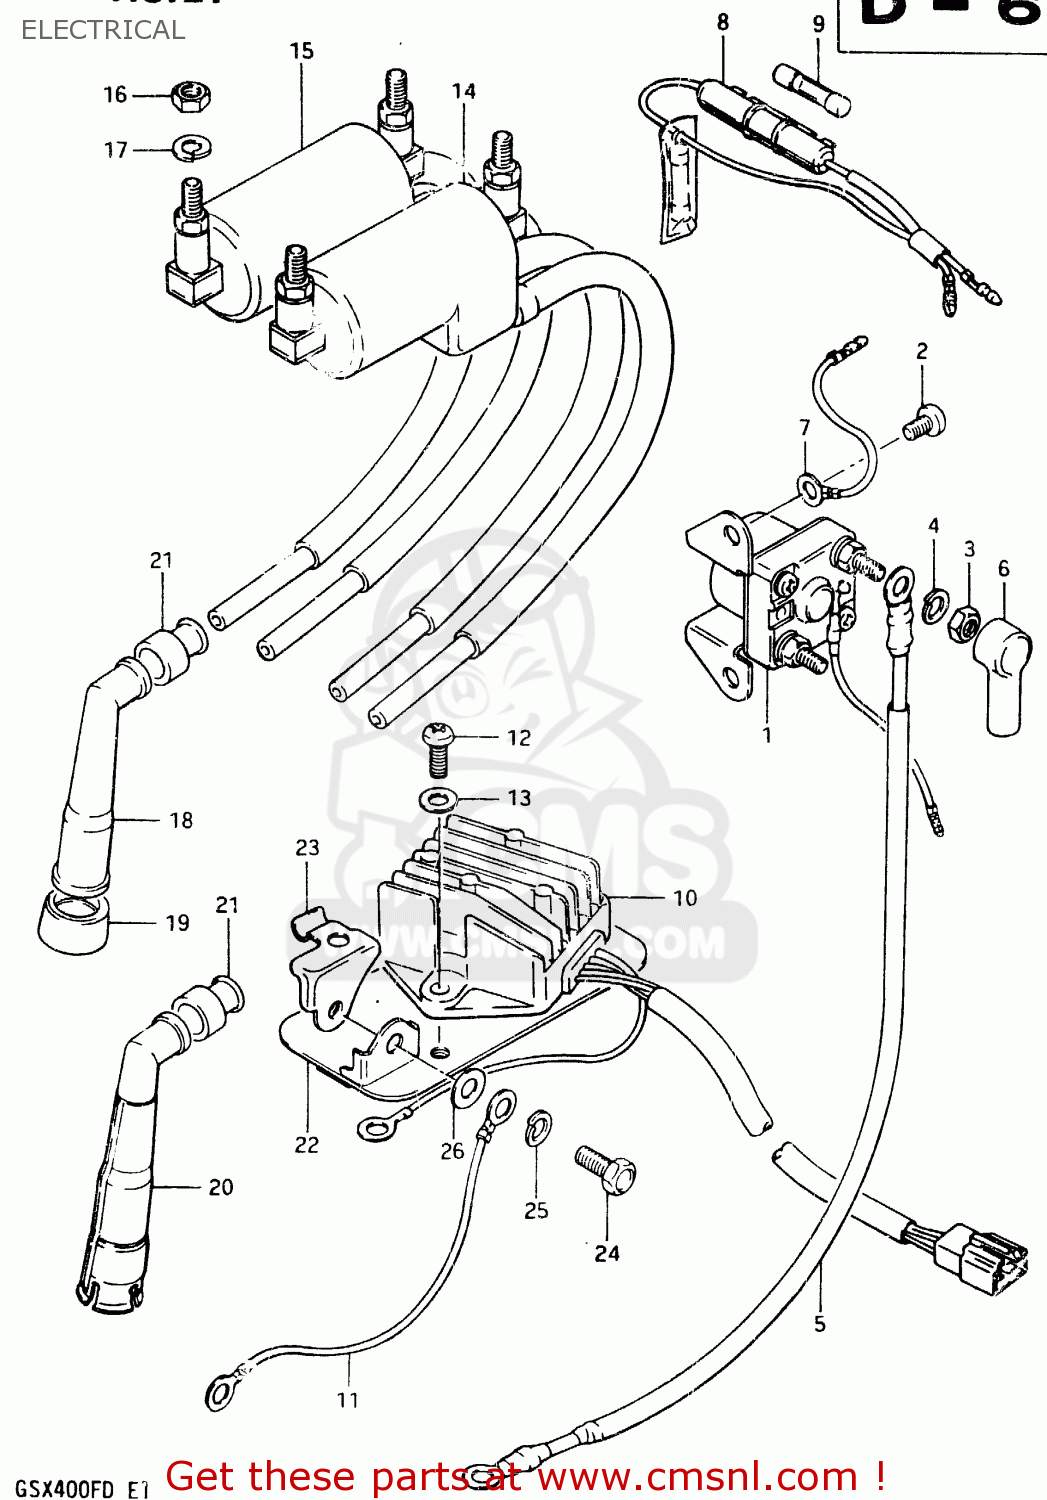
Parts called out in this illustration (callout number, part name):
1	RELAY ASSY,STARTING MOTOR
2	SCREW
3	NUT 6MM
4	LOCK WASHER
5	WIRE,STARTER MOTOR LEAD
6	CAP,STARTER RELAY
7	LEAD WIRE
8	BOX ASSEMBLY,FUSE
9	FUSE(15A)
10	RECTIFIER ASSEMBLY
11	LEAD WIRE,EARTH
12	SCREW
13	WASHER
14	COIL, IGNITION NO. 1
15	COIL, IGNITION NO. 2
16	NUT
17	LOCK WASHER
18	CAP ASSY,SPARK PLUG
19	SEAL,SPARK PLUG
20	CAP, SPARK PLUG
21	SEAL,SPARK PLU
22	PLATE, PARTS HOLDER
23	BRACKET
24	BOLT, UPPER
25	LOCK WASHER
26	WASHER
